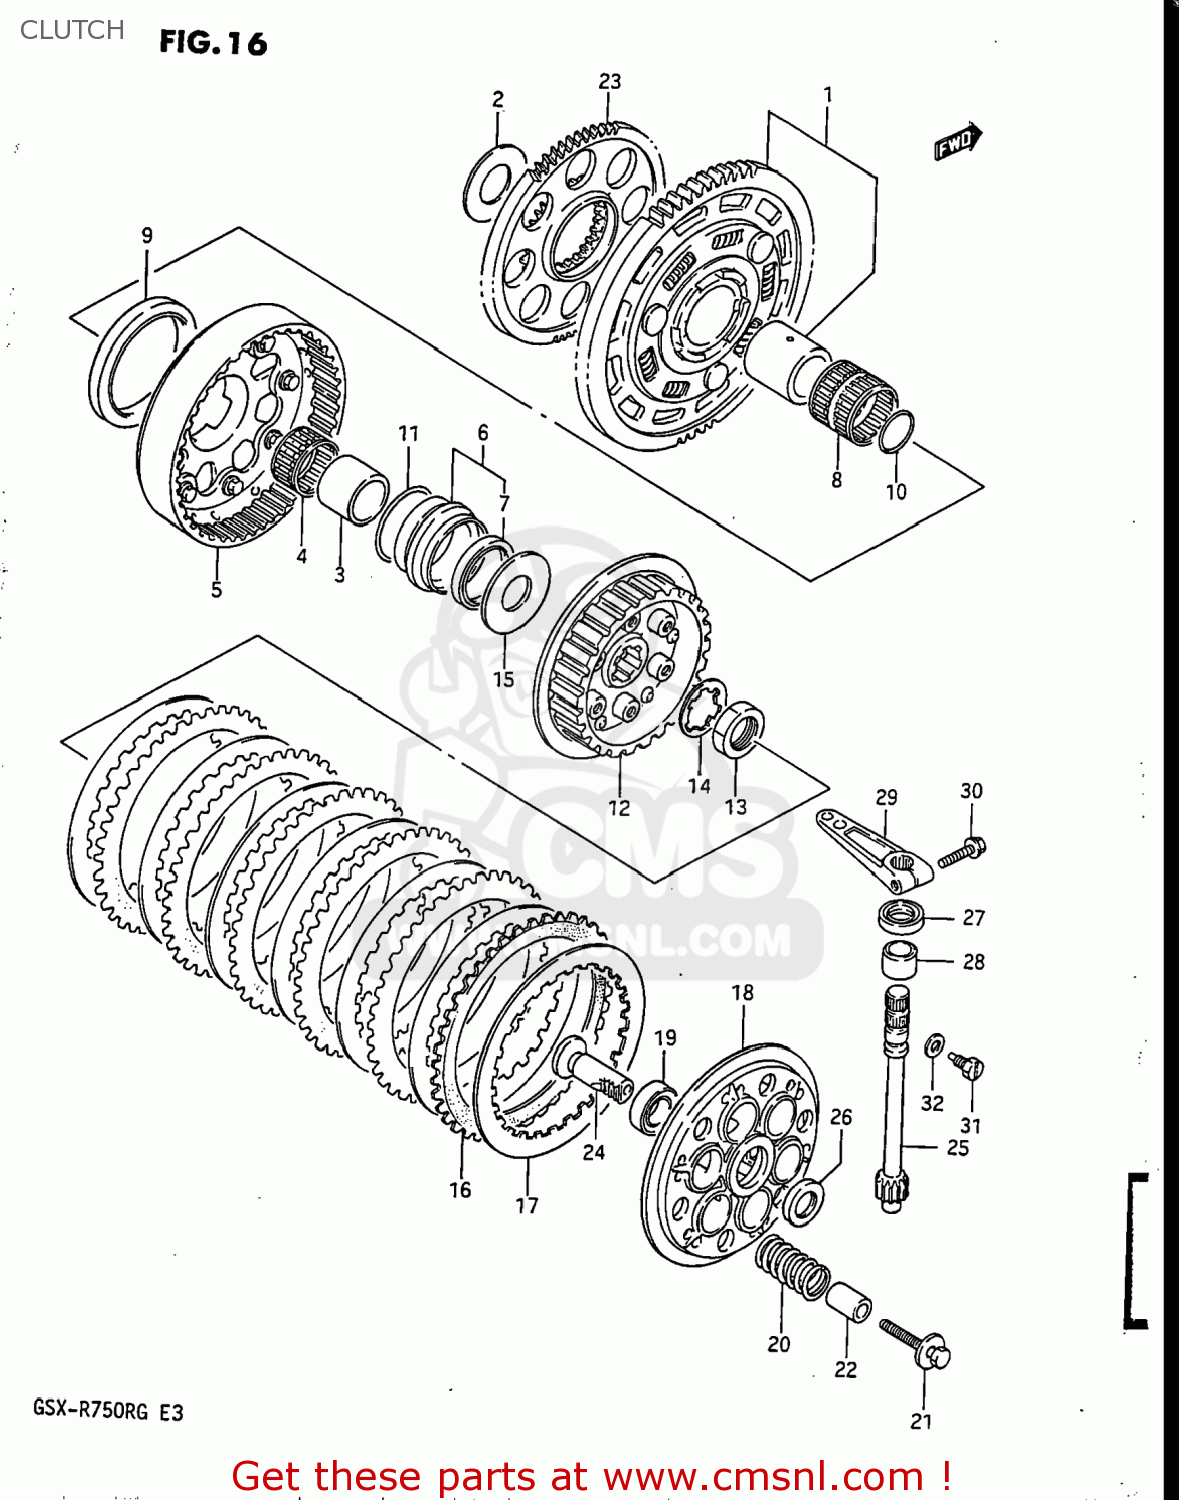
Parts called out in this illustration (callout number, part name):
1	GEAR ASSEMBLY,PRIMARY DRIVE
2	WASHER
3	SPACER(25X35X25.4)
4	ROLLER BEARING,PRIMARY DRIVE
5	HOUSING,CLUTCH
6	COLLAR,CLUTCH HOUSING
7	SEAL,OIL(35X45X6)
8	BEARING(35X40X35.8)
9	SEAL,OIL(62X82X7)
10	O-RING
11	O-RING (D:2.4 ID:45.7)
12	HUB,CLUTCH SLEEVE
13	NUT
14	WASHER,LOCK
15	WASHER (22X51X2.5)
16	PLATE,CLUTCH DRIVE
17	PLATE,CLUTCH DRIVEN
18	PLATE,CLUTCH PRESSURE
19	SPRING,CLUTCH
20	SPRING
21	BOLT
22	SPACER(6.2X12.6X21)
23	GEAR,GENERATOR DRIVE
24	RACK,CLUTCH RELEASE
25	PINION,CLUTCH RELEASE
26	SEAL,OIL(15X25X4)
27	SEAL,OIL(13X23X5)
28	BUSHING,CLUTCH RELEASE PIN
29	ARM,CLUTCH RELEASE
30	BOLT
31	BOLT
32	WASHER
